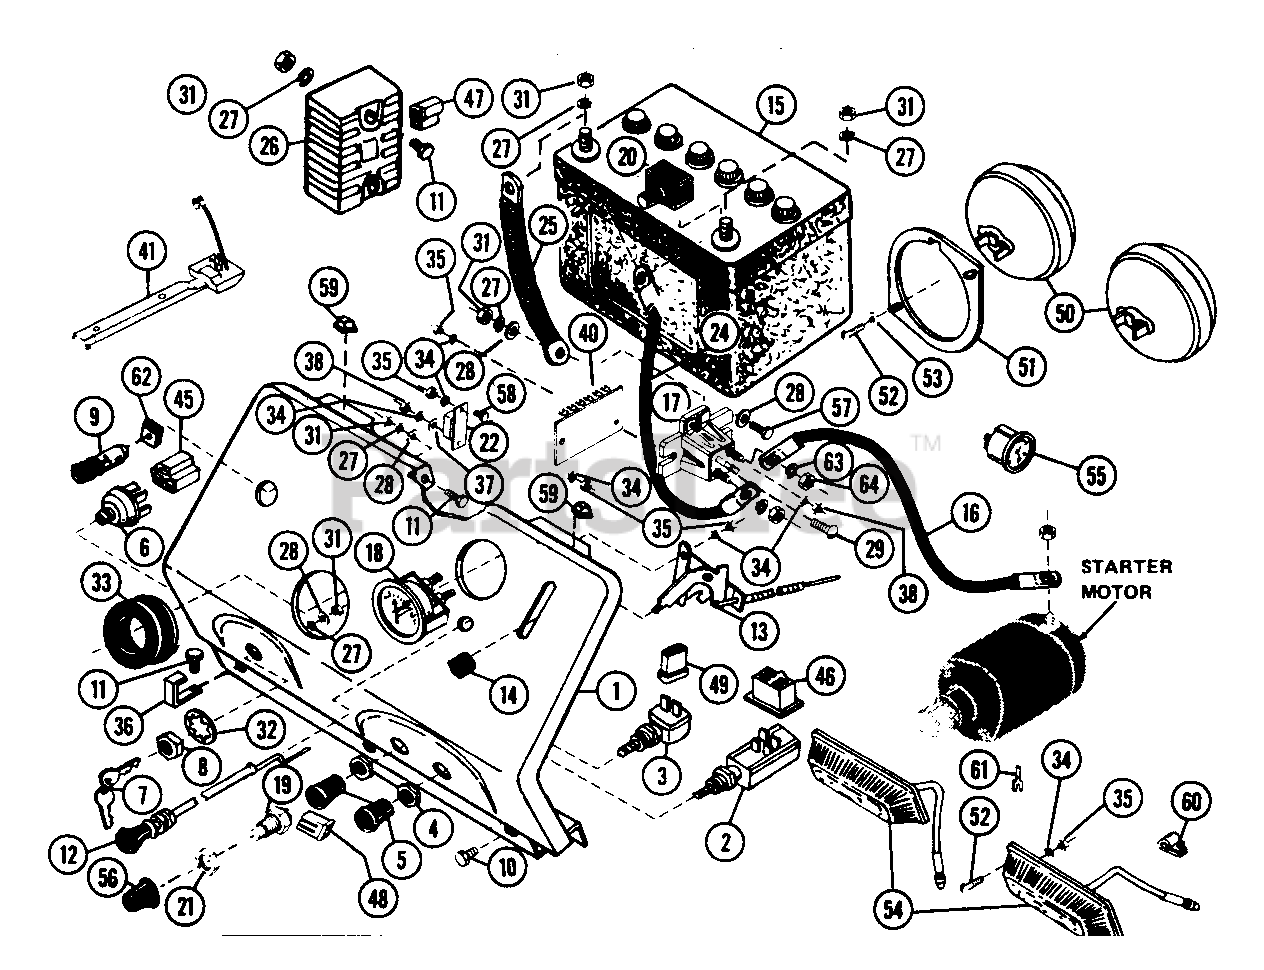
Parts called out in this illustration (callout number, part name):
1	DASH ASSEMBLY - T17 & S18
2	CLUTCH SWITCH
3	LIGHT SWITCH
4	NUT .50-20 PL
5	KNOB
6	SWITCH & KEY SET ASSEMBLY
7	KEYS
8	NUT .562-24
9	PTO INDICATOR LIGHT
10	SCR-TAP 10-16X.50 HWH PL AB
11	BLT-HEX .25-20X.75 PL GR2
12	CHOKE CONTROL
13	THROTTLE CONTROL
15	BATTERY
16	GROUND CABLE .31X22.00X.31
16	GROUND CABLE
17	SOLENOID
18	AMMETER
19	SAFETY SWITCH
20	INSULATOR
21	NUT-HEX .625-32 PL
22	CIRCUIT BREAKER
24	GROUND CABLE .25X6.50X.31
25	GROUND CABLE
26	REGULATOR RECTIFIER
27	WSHR-LK .250X.077 HVY PL
28	WSHR-FL-STL.281X.62X.065 PL
29	SCR-MCH 10-24X.50 SLRH PL
31	NUT-HEX .250-20 PL
32	WSHR-LK-INT .563X.040 PL
33	GROMMET
34	WSHR-LK 10X.047 MED PL
35	NUT-HEX 10-24 PL
37	WSHR-FL-STL .219X.500X.049 PL
38	NUT 10-32 PL
40	INTERLOCK MODULE
41	SWITCH SEAT
45	CONNECTOR HOUSING
46	CONNECTOR
47	CONNECTOR
48	CONNECTOR
49	CONNECTOR
50	HEAD LIGHT
51	HEAD LIGHT RETAINER RING
52	SCR-MCH 10-24X.50 SLTR PL
53	WSHR-FL-STL .250X.562X.049 PL
54	TAIL LIGHT
55	HOUR METER
57	BLT-HEX .25-20X1.00 GR2
58	SCR-MCH 10-24X.50 SLTR PL
59	STOP
60	WIRE CLIP
61	MALE DISCONNECT ADAPTER
62	SPEED NUT
63	WSHR-LK .312X.097 PL HVY
64	NUT-JAM .312-24 PL
